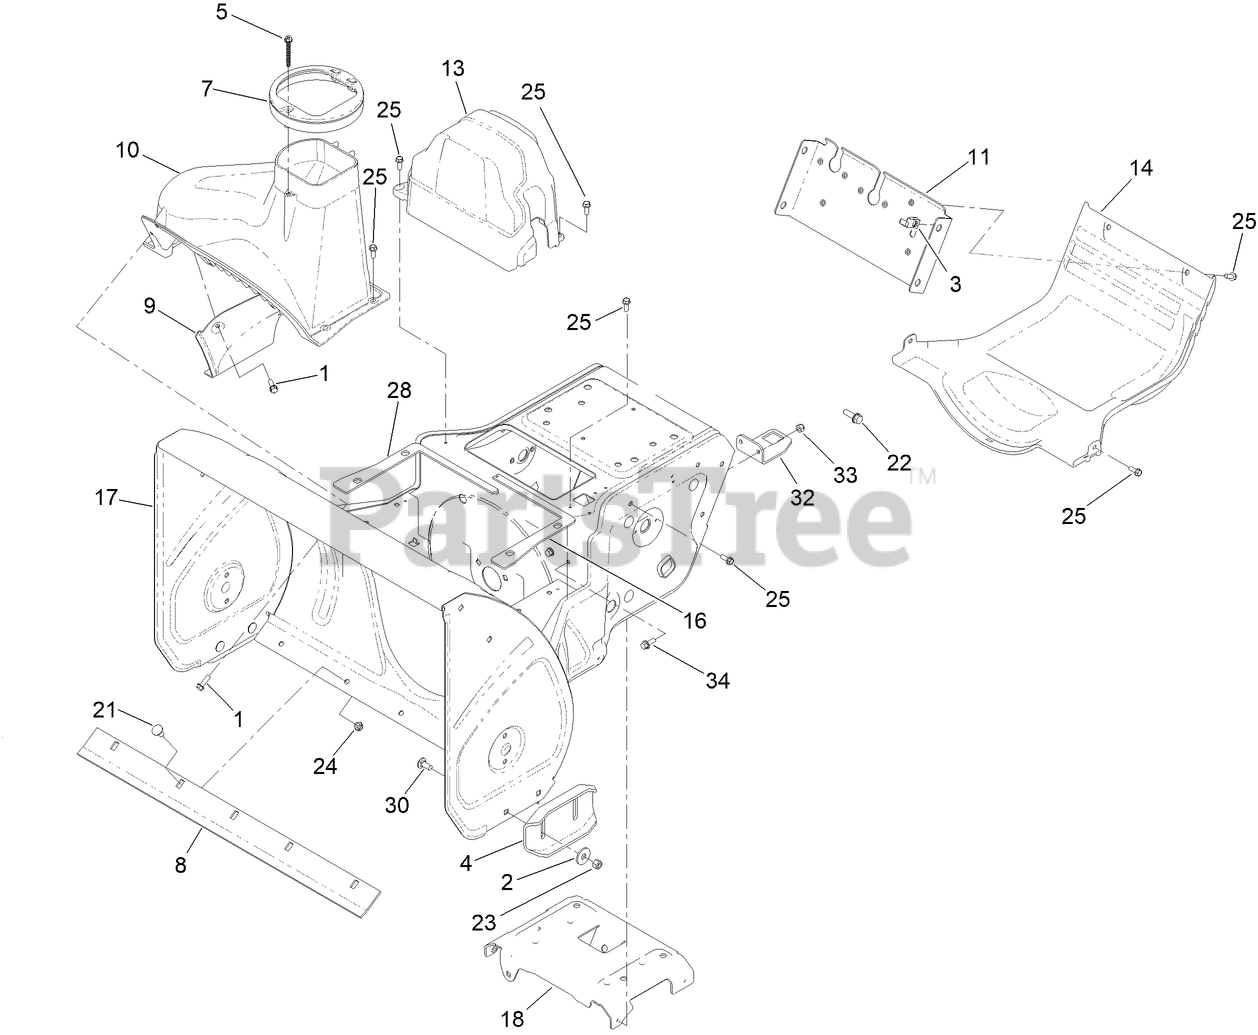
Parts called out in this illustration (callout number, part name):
1	SCREW-HWH
2	WASHER
3	NUT-U
5	SCREW-HWH, PLASTITE
7	GUIDE-CHUTE
8	SCRAPER-26 INCH
9	COVER-LINER
11	BRACE-FRAME
13	COVER-BELT
14	COVER-LOWER
16	SEAL-HOUSING, LH
17	FRAME ASM
18	BRACE-FRAME
21	SCREW-CARR
22	SCREW-HHF
23	NUT-LOCK, NI
24	NUT-LOCK, NI
25	SCREW-HWH
28	SEAL-HOUSING, RH
30	SCREW-CARR
32	BRACKET-POST, CHUTE
33	SCREW-HHF
34	NUT-HEX
